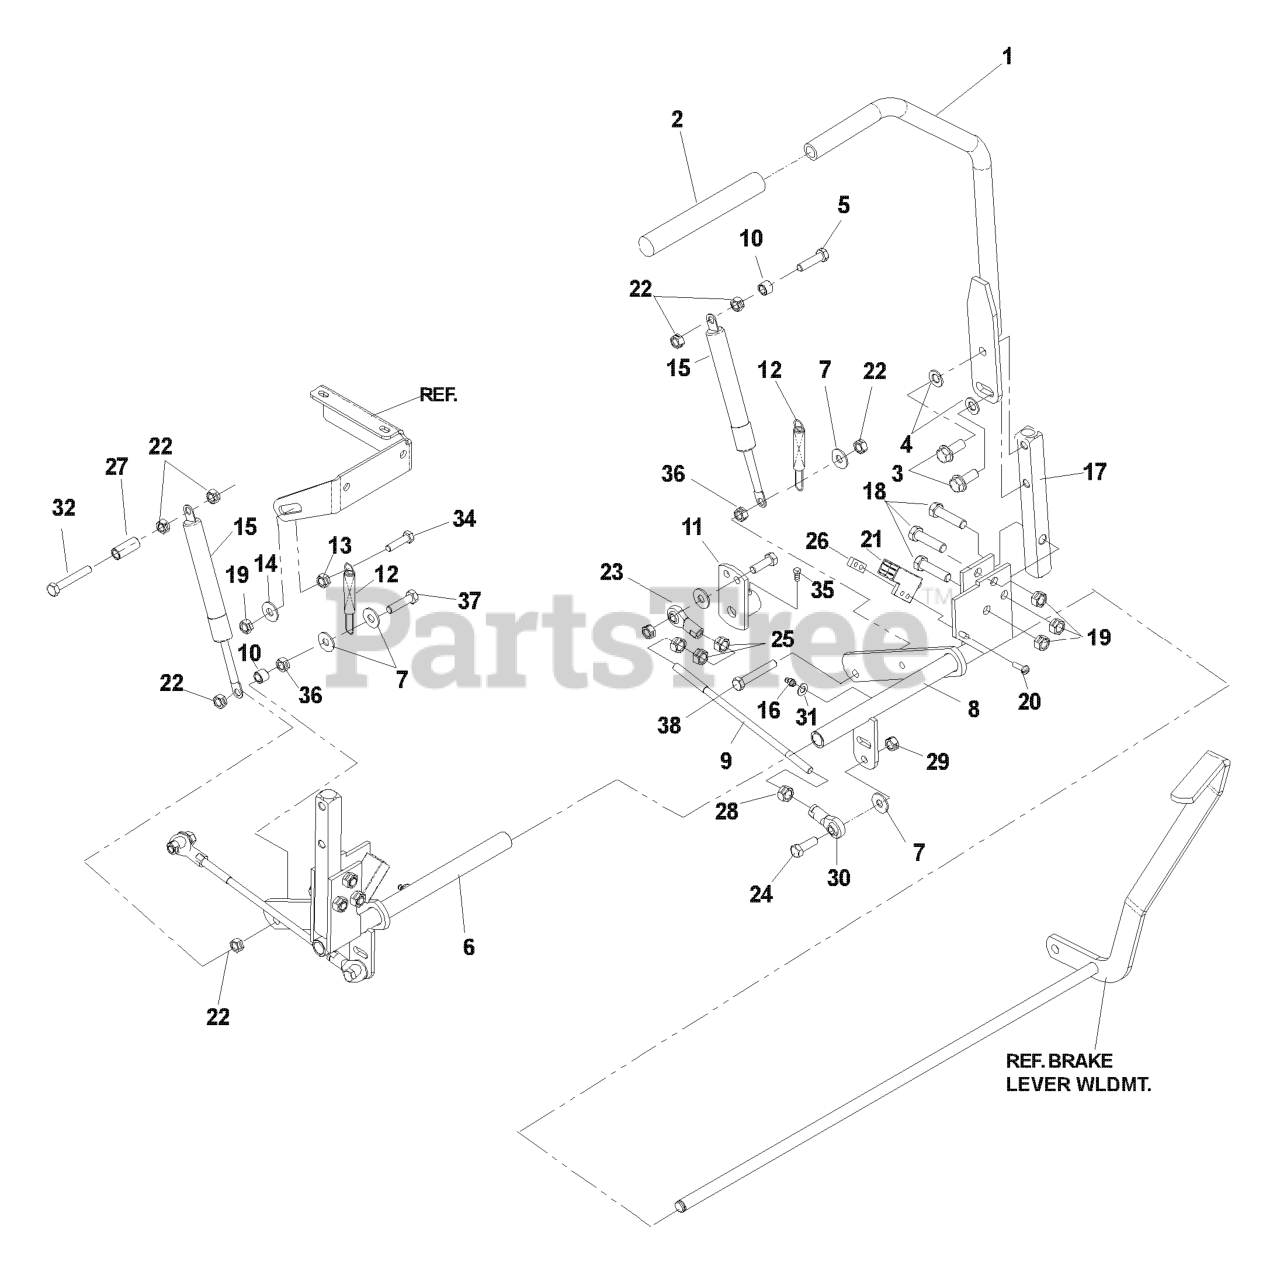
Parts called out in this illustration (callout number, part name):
1	CONTROL LEVER WELDMENT
2	GRIP, PARK BRAKE
3	HCS 3/8-16X1.GRD.5.ZD
4	WASHER, 3/8 DISC SPRING SPEC
5	CAPSCREW 5/16 X 1/1/2 HEX HEAD
6	CONTROL WLDMNT RH
7	WASHER 5/16 FLAT
8	CONTROL WLDMNT - LH
9	PUMP CONTROL LINK
11	PUMP LEVER
13	NUT 3/8C WHIZ
14	WASHER 3/8 FLAT
16	ZERK
17	CONTROL ARM
18	HCS 3/8-16 X 1 3/4 GR5
19	NUT 3/8-16 NYLOC
20	SCREW #10-24 X 5/8
21	SWITCH, INTERLOCK
22	NUT 5/16C CENTERLOCK
23	BALL JOINT, RIGHT HANDED
24	HCS 5/16C X 1 1/4
26	TAPPED PLATE
28	NUT 5/16F LEFTHAND
29	NUT 5/16 NYLOC
30	BALL JOINT, LEFT HANDED
32	HCS 5/16-18X2
34	HCS 3/8C X 2 1/2
35	5/16C X 5/8 "V" POINT
36	NUT 5/16C WHIZ
37	TAP BOLT 5/16C X 2 1/4
38	BOLT, TAP 5/16-18
